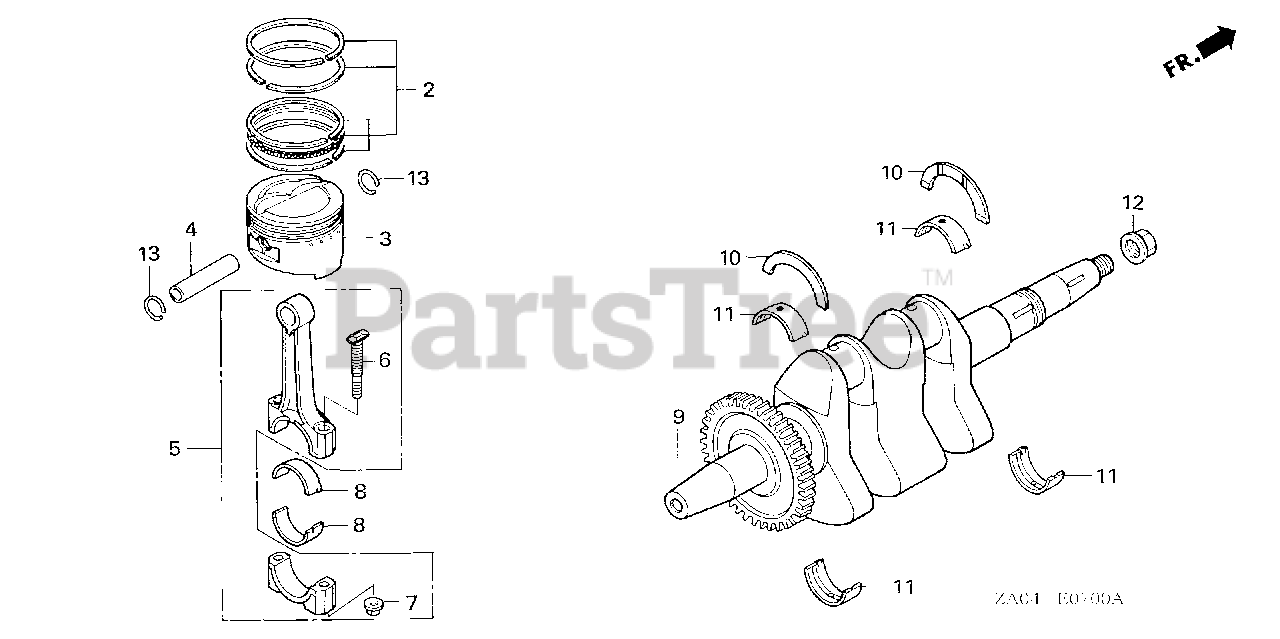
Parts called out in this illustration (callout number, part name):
2	RING SET, PISTON (STD) (RIKEN)
2	RING SET, PISTON (0.25) (RIKEN)
2	RING SET, PISTON (0.25) (TEIKOKU)
2	RING SET, PISTON (0.50) (TEIKOKU)
3	PISTON (STD)
3	PISTON (0.25)
3	PISTON (0.50)
4	PIN, PISTON
5	ROD ASSY., CONNECTING
6	BOLT, CONNECTING ROD
7	NUT, CONNECTING ROD
8	BEARING A, CONNECTING ROD (BLACK)
8	BEARING B, CONNECTING ROD (BROWN)
8	BEARING C, CONNECTING ROD (GREEN)
8	BEARING D, CONNECTING ROD (YELLOW)
8	BEARING E, CONNECTING ROD (RED)
9	CRANKSHAFT
10	BEARING, CRANKSHAFT THRUST
11	BEARING, CRANKSHAFT (BLACK)
11	BEARING, CRANKSHAFT (BROWN)
11	BEARING, CRANKSHAFT (GREEN)
11	BEARING, CRANKSHAFT (YELLOW)
11	BEARING, CRANKSHAFT (RED)
12	NUT, FLANGE (16X1.0)
13	CLIP, PISTON PIN (14MM)
